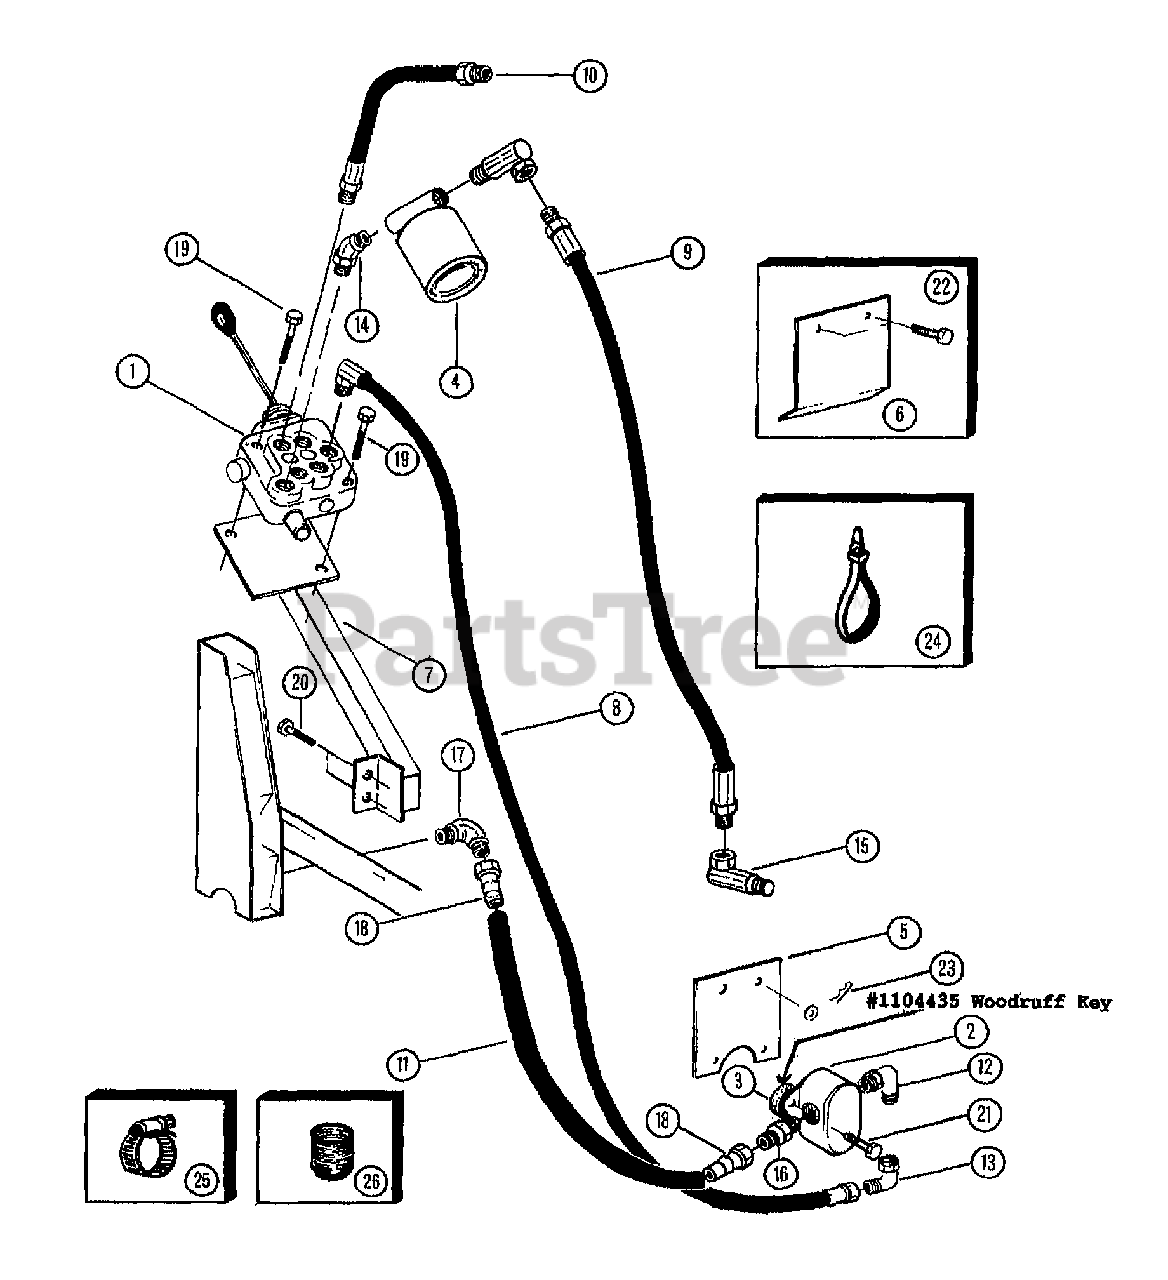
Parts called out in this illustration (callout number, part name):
1	ASSM-VALVE HYDRAULIC
4	FILTER-OIL
7	STAND-VALVE
12	FITTING-ADAPTOR
13	FITTING-ADAPTOR 90
14	FITTING-ADAPTOR
15	FITTING-ADAPTOR
16	FITTING-ADAPTOR
18	HOSE-END
23	CLIP-HAIRPIN .07 DIA
